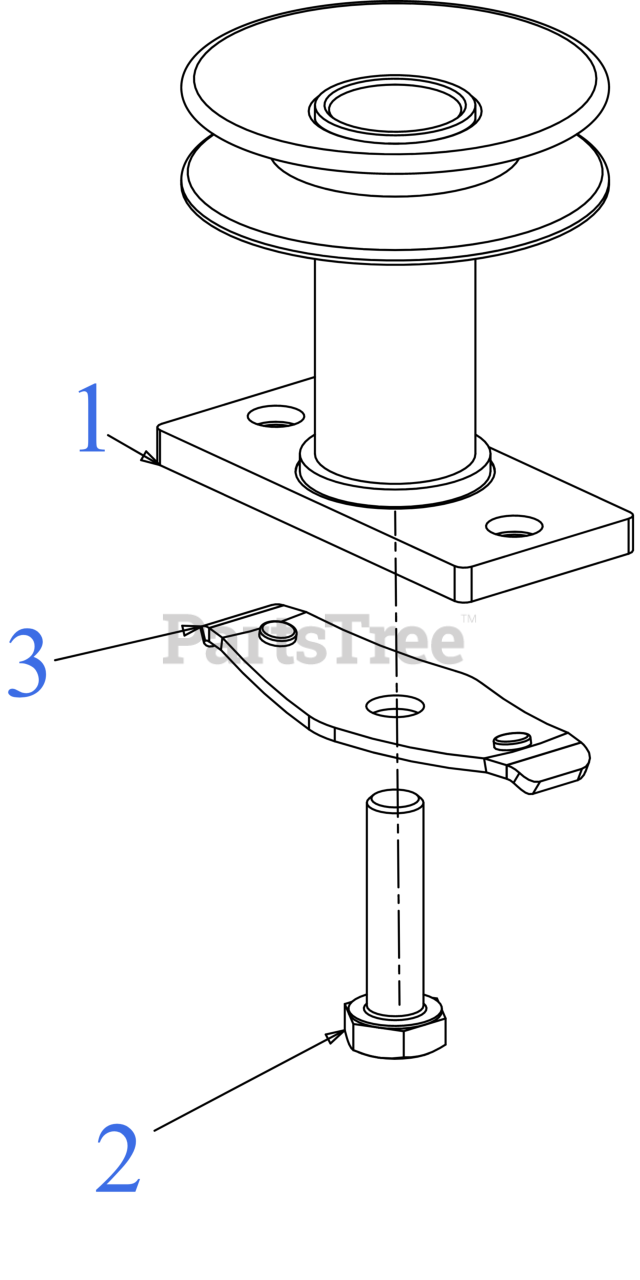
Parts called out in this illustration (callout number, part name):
1	ADAPTER ASSEMBLY (7/8 ID x .430 SP)
2	SCREW 3/8-24 x 1.50 GR8
3	BLADE BELL SUPPORT
